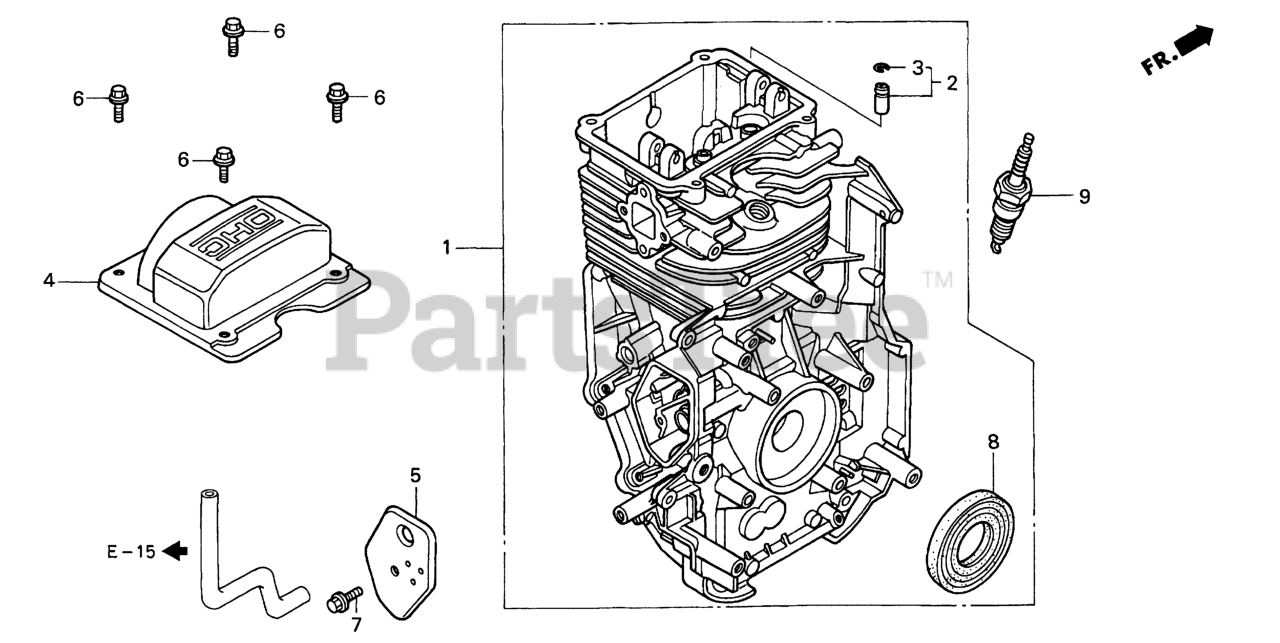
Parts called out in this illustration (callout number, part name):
1	CYLINDER ASSY.
3	CLIP, VALVE GUIDE Use from Engine SN 1231803.
4	COVER, CYLINDER HEAD
5	COVER, BREATHER (Honda Code 5580006). (BREATHER VALVE ASSY.)
6	BOLT, FLANGE (6X12) (CT200)
7	BOLT, FLANGE (6X14)
8	OIL SEAL (25.4X62X6)
9	SPARK PLUG (BPR6ES) (NGK)
